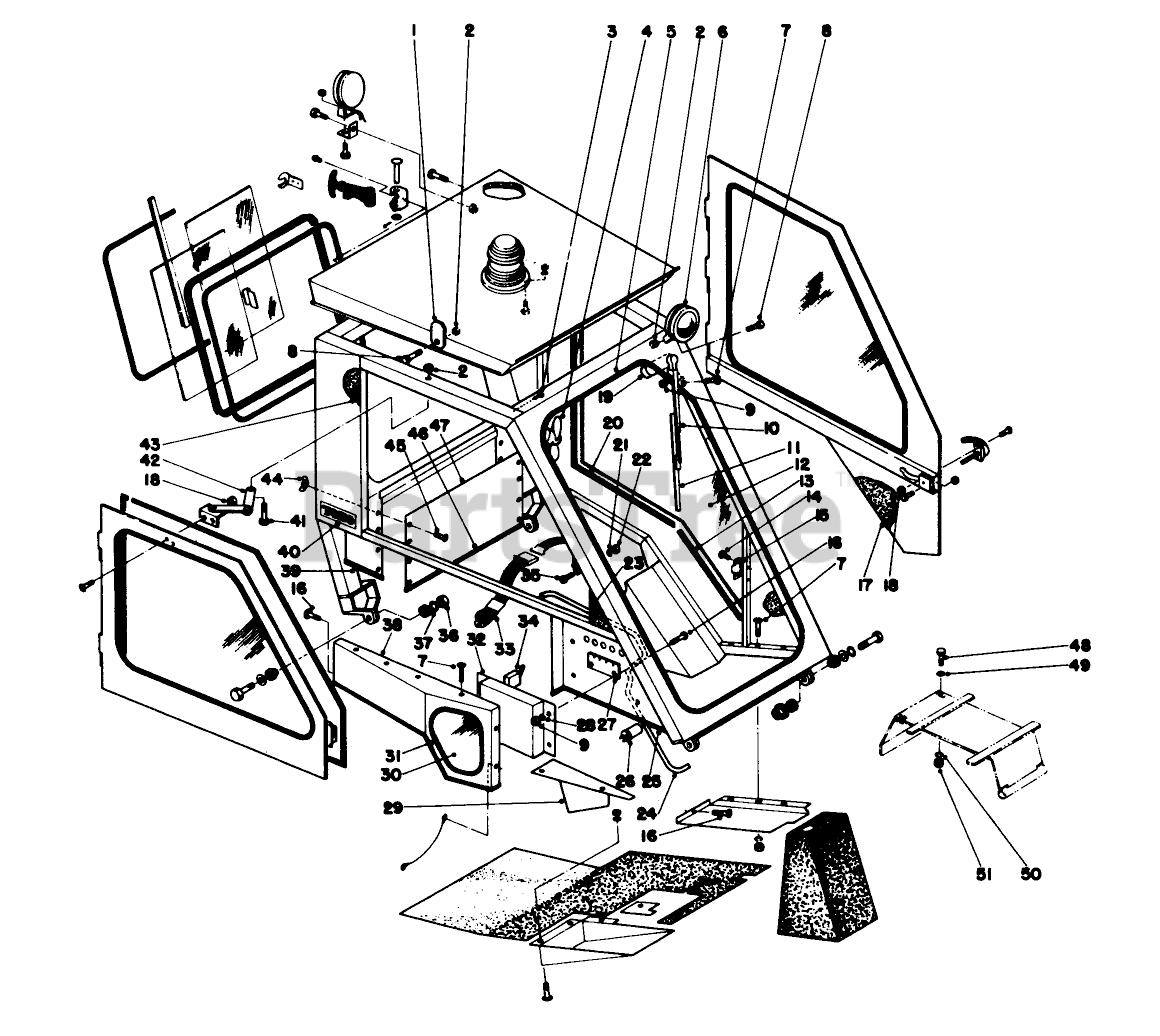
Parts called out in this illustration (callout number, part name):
1	SPRING
3	NUT-HF
4	DECAL-DANGER
5	NUT-HEX
6	DECAL-DANGER
8	DECAL-DANGER, THROWN OBJECT
9	WASHER-FLAT
11	NUT-HHF, WHIZ
12	WASHER-FLAT
13	NUT-LOCK, NI
14	PLATE-IDLER
15	KEY-SQUARE
17	PULLEY-IDLER
18	WASHER-FLAT
19	ROLLER-DECK
20	PIN-COTTER
21	SHAFT-ROLLER, REAR
22	V-BELT
23	FITTING-GREASE
24	NUT-HEX
25	WASHER
27	SEAL-OIL
28	BEARING ASM
29	SCREW-CARR
31	DECAL-TORQUE
32	HOUSING-SPINDLE
33	NUT-HF
34	SHAFT
36	CUP-SCALP, ANTI
37	WASHER-LOCK
38	SCREW-BLADE
39	SPACER
41	SHAFT-ROLLER
42	PIN-SPECIAL
43	ROLLER
44	SCREW-HH
45	BUSHING-PULLEY
46	SCREW-CARR
47	SCREW-HH
49	DECAL-DANGER
